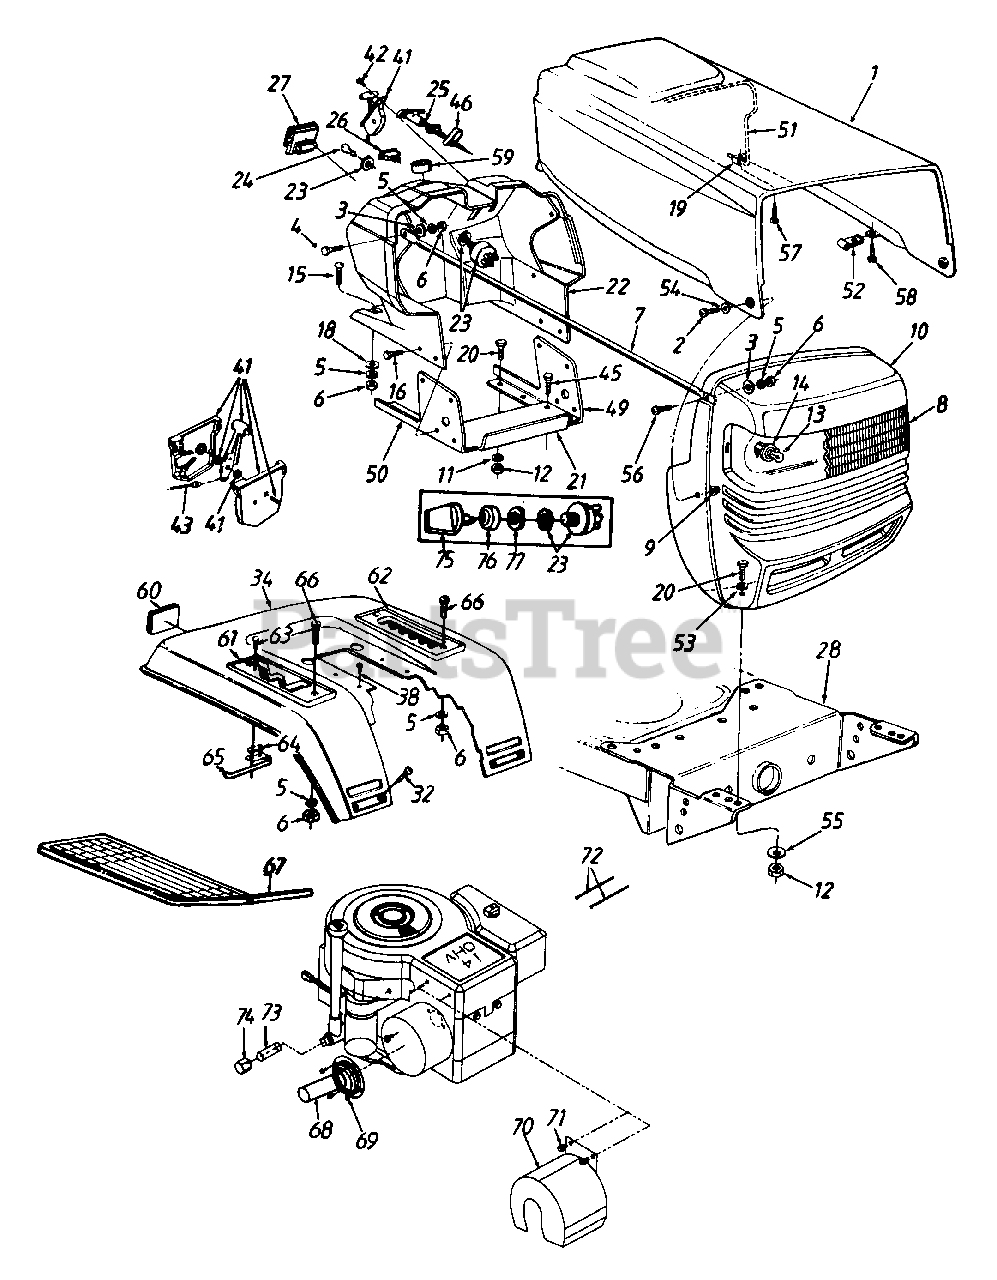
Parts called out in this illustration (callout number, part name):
3	Fl-Wash. .28" I.D. x .75" O.D.
4	Hex Bolt 1/4-20 x .62" Lg.
5	L-Wash. 1/4" I.D.
6	Hex Nut 1/4-20 Thd.
9	Flange L-Nut 1/4-28 Thd.
12	Hex Nut 5/16-18 Thd.
13	Lamp
14	Socket
15	Carriage Bolt 1/4-20 x .75" Lg.
16	Hex Wash. Hd. TT-Tap Scr. 1/4-20 x .5" Lg.
18	Bolt Retainer 1/4" I.D.
19	Speed Nut #10-24 Thd.
20	Hex Bolt 5/16-18 x .75" Lg.
23	Ignition Switch
24	Ignition Key
25	Choke Control
26	Light Switch
27	Ammeter
32	Truss Mach. Scr. 1/4-20 x .5" Lg.
41	Throttle Box Ass'y.
42	Truss Mach. AB-Tap Scr. #10 x .5" Lg.
43	Throttle Control Wire
45	Hex Wash. Hd. 8-Tap Scr. 5/16-18 x .5" Lg.
46	Choke Retainer
52	Speed Nut #10-16 Thd.
53	Fl-Wash. .344" I.D. x 1" O.D.
54	Spr. Wash. .39" I.D. x .62" O.D.
55	Bell-Wash. .345" I.D. x .88" O.D.
56	Truss Mach. Scr. 1/4-20 x .75" Lg.
57	Pan Hd. Scr. #10-24 x .75" Lg.
58	Truss Mach. B-Tap Scr. #10 x .5" L.g.
59	Steering Column Brg.
60	Reflector
61	Forward/Reverse Index Brkt.
62	7-Speed Index Brkt.
63	Hex Wash. Hd. AB-Tap Scr. #8 x .5" Lg.
64	Insulator Nut Plate
65	Reverse Safety Switch
66	Truss Mach. Scr. 1/4-20 x .75" Lg.
67	Foot Pad - L.H.
68	Exhaust Pipe Ass'y.
69	Hex Wash. Hd. F-Tap Scr. #8-32 x .38" Lg.
70	Heat Shield Ass'y.
71	Hex Wash. Hd. Scr. 1/4-20 x .5" Lg.
72	Cable Tie
73	Pipe Nipple 3/8-18 NPT x 2" Lg.
74	Cap - Oil Drain
75	Ignition Key
76	Ignition Switch Cap
77	Ignition Switch Nut
